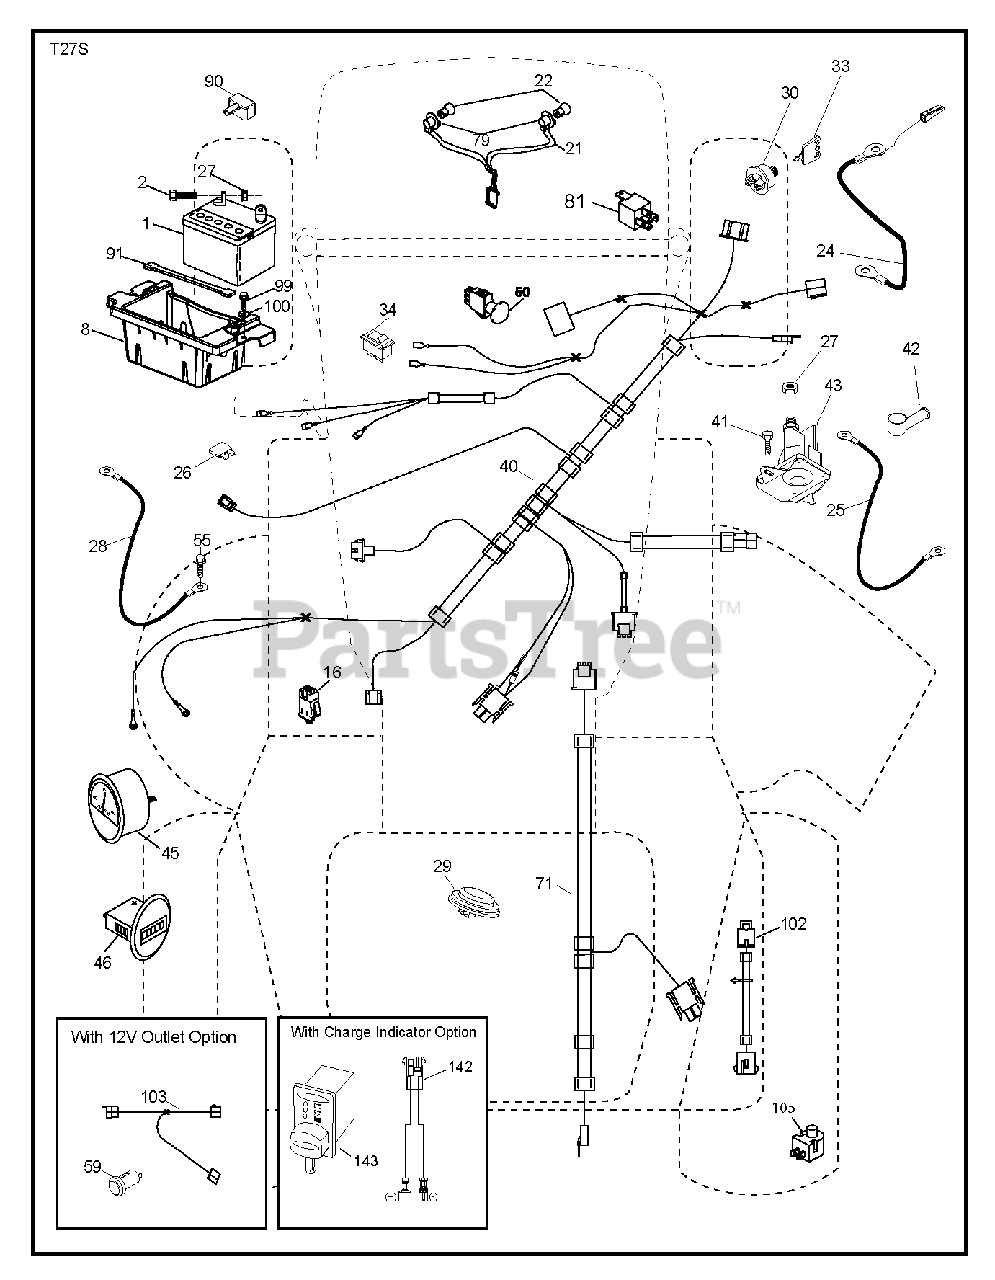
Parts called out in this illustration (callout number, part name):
1	Battery, Dry 30 Amp
2	BOLT.HEX.1/4.X.3/4.DICHROMATE
8	BOX.BATTERY.MOUNT.FRONT.LT
16	SWITCH INTERLOOK PUSH-IN
21	HARNESS.LIGHT W/4152J BULBS
24	CABLE.BATT.POS.WIRE.TG.DA SOL
25	CABLE.STARTER.6G.BL/RED.17.5
26	FUSE 20AMP
27	NUT
28	CABLE GROUND 6 GA 21" 90T BLK
29	SWITCH.SEAT.DELTA.OPC.
30	SWITCH.IGN.DELTA.W.LGH.ROS
33	KEY.CHAIN.BLISTER.PACK.GEN.USA
40	HARNESS.IGN.ELE.RELAY.RND.TEX
41	SCREW
42	TERMINAL COVER
43	SOLENOID.W/BRASS.PLUNGER
45	AMMETER GAUGE ROUND SNAP-IN
46	HOURMETER.GAUGE.RNK.SNAPIN.LS
50	RB PTO.SWITCH.8 TERMINAL.BLACK
55	SCREW 5/16"
59	OUTLET.12-VOLT
71	HARNESS-CHASSIS SUB
79	BULB HOLDER ASM.
81	RELAY HARNESS.SEALED
90	COVER.TERMINAL.BATTERY
91	STRAP.BATTERY.MOUNT.FRONT(2 2)
99	SCREW HEXWSHR 1/4-20X3/4
102	HARNESS PIGTAIL PCH TEX ROS
103	HARNESS.PIGTAIL.12V.OUTLET.
105	REVERSE SWITCH
142	RP HARNESS.JUMPER.CTEK
143	SWITCH.ON/OFF.(DIFF.LOCK)
